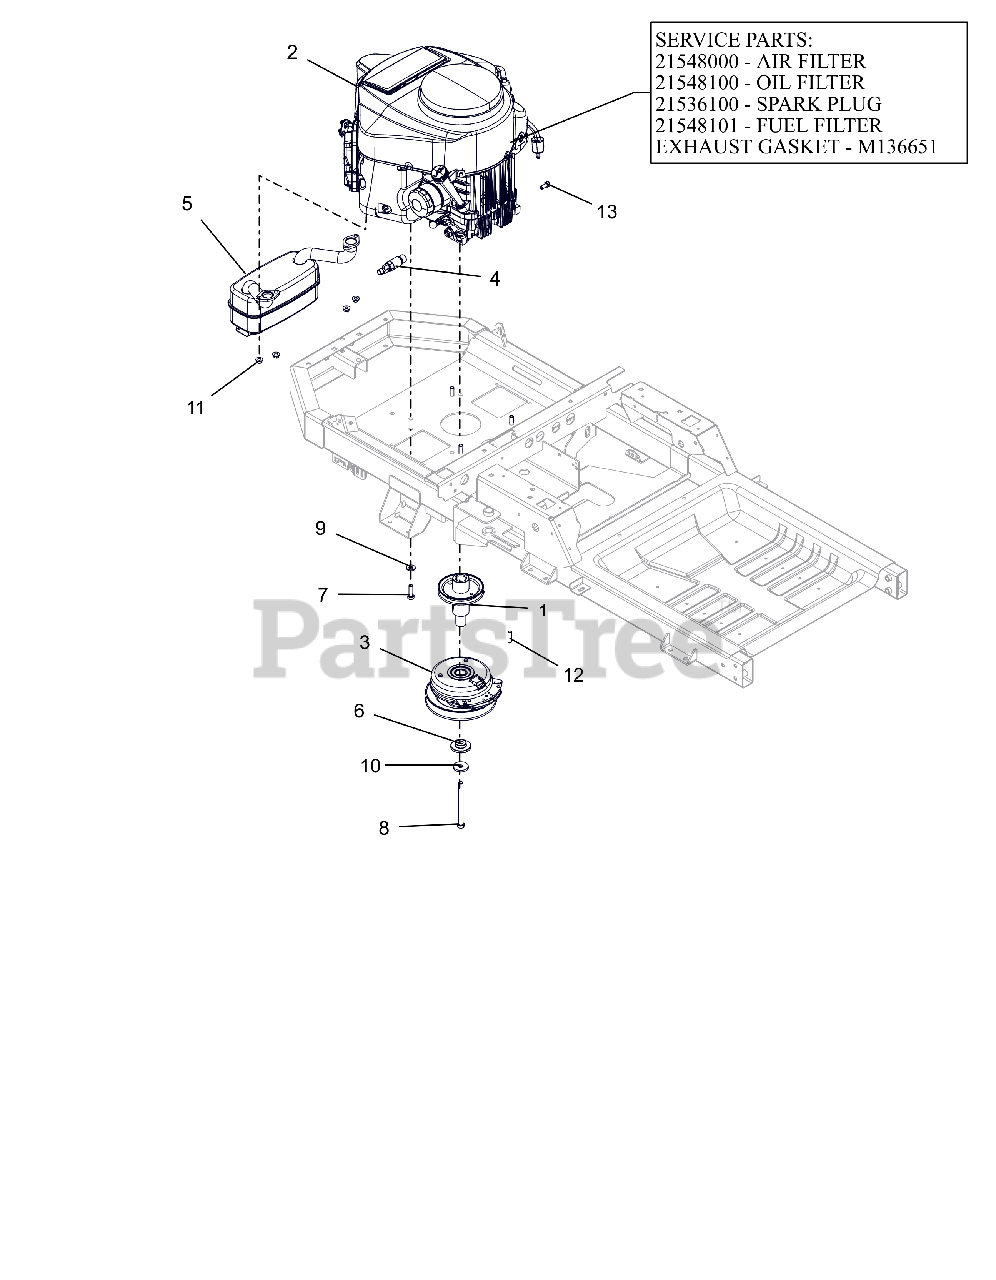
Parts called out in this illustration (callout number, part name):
1	WLDMT, DRIVE SHEAVE (LG XL)CZC
2	ENGINE, KAWASAKI FR730 24HP
2	AIR FILTER, KAWASAKI FR
2	OIL FILTER, KAWASAKI FR
2	PLUG, SPARK
2	FUEL FILTER-KAWASAKI FR
2	GASKET, MUFFLER #
3	CLUTCH,105FTLB MONOPOLE 6.83"
4	DRAIN, OIL M20X2.5
5	MUFFLER - KAWASAKI
6	BSHG-FLG .469X1.06X.574X2.0
7	BLT, HEX .38-16X1.25 G5 ZCC NT
8	BLT-HEX.438-20X5 GR8 YZ NYTORQ
9	WASHER, 3/8" SPRING DISC
10	WASHER, 7/16" SPRING DISK
11	NUT-LK-TOP-FLG M8 ZCC
12	KEY-SQ .25 X 1.25 X .25 SAE
13	BLT, HEX M8-1.25X20 G8.8 ZCC
